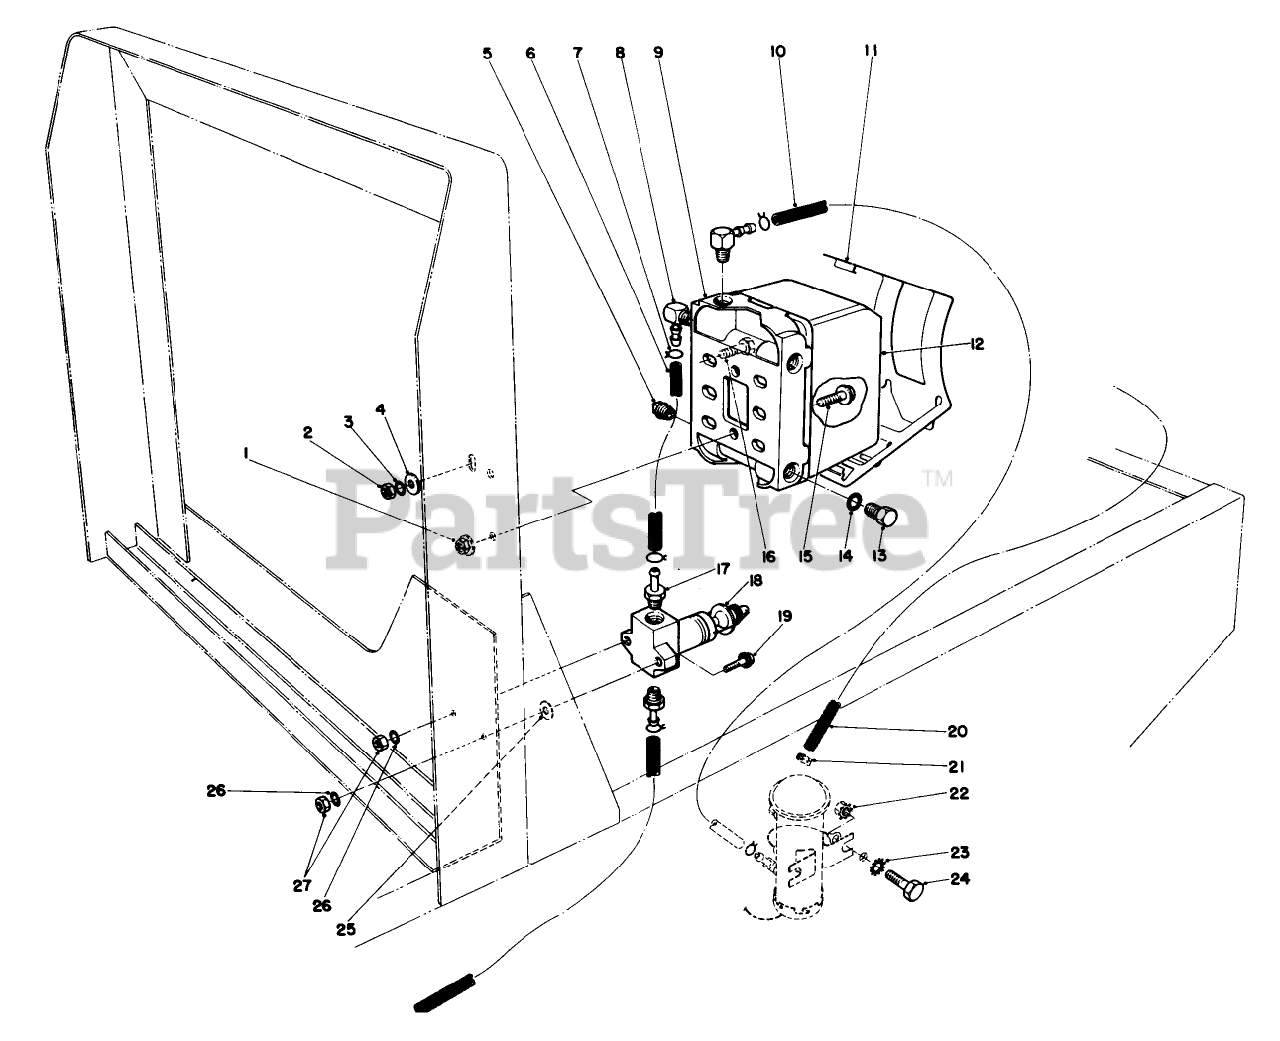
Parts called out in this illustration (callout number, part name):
1	NUT-HHF, WHIZ
2	NUT-HEX
3	WASHER-LOCK
4	WASHER-PLAIN
5	PIPE PLUG
6	Hose Fuel
7	CLAMP-HOSE
8	FITTING-ELBOW
9	SEP BASE SUB-ASM
10	Hose
11	WATER SEPARATOR CLAMP
12	SEPARATOR ELEMENT
13	DRAIN/VENT PLUG
14	DRAIN/VENT WASHER
15	SCREW-HHF
16	SCREW-HH
17	FITTING-STRAIGHT
18	PRIMER PUMP
19	CAPSCREW 10-24 X 1
20	Hose
21	CLAMP-HOSE
22	NUT-KEPS
23	WASHER-LOCK/EXT
24	SCREW-HH
25	WASHER-PLAIN
26	WASHER-LOCK
27	NUT-HEX
